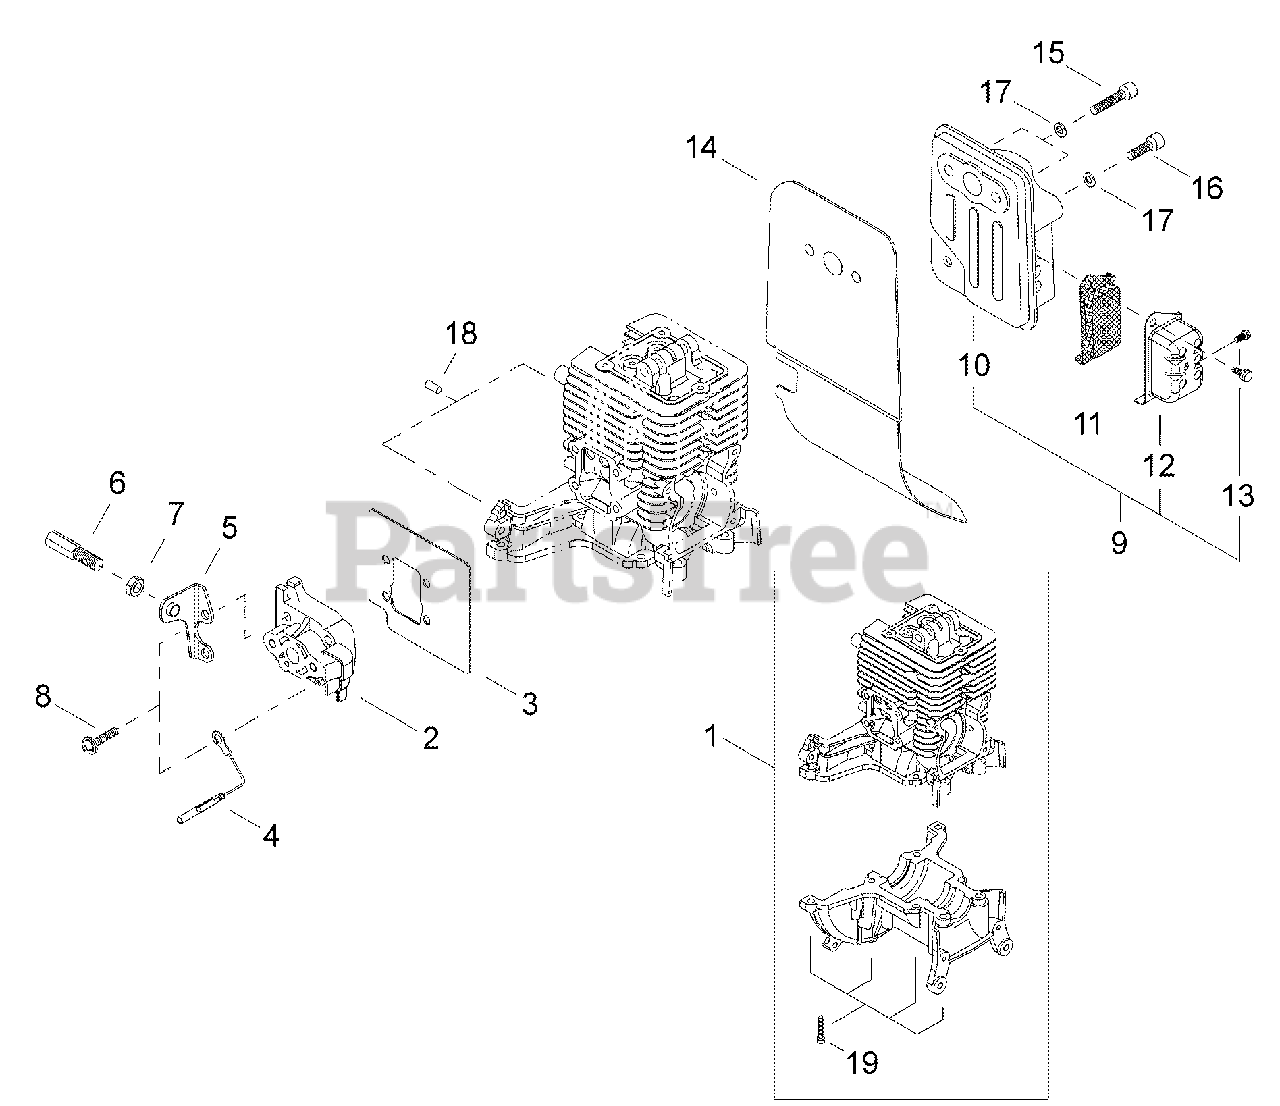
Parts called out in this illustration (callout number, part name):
1	CYLINDER BLOCK SET
2	VALVE, REED
3	DEFLECTOR, HEAT
4	LEAD - GROUND
5	BRACKET, THROTTLE CABLE
6	NUT, CABLE ADJUST
7	LOCKNUT - 6
8	SCREW - 5X25
9	MUFFLER ASSY
10	MUFFLER
11	SCREEN, SPARK ARRESTOR
12	GUIDE, EXHAUST
13	SCREW - 4X6
14	SHIELD, EXHAUST
15	SCREW - 5X25
16	SCREW - 5X16
17	WASHER - 5
18	PIN - LOCATING
19	SCREW - 5X16
